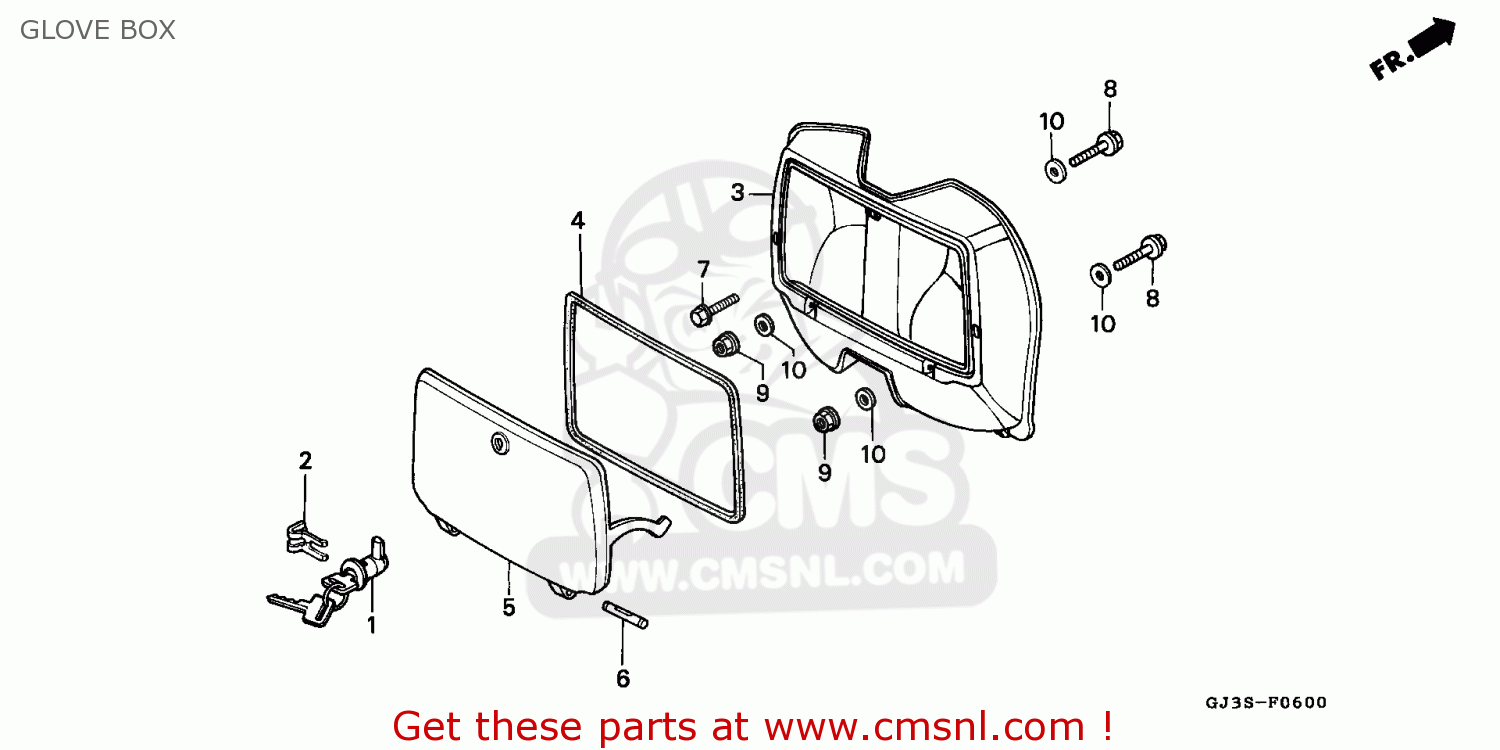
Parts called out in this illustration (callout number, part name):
1	KEY SET,(GLOVE BO
2	SPR DR LOCK KEY
3	GLOVE BOX PB190
4	RUBBER C,SEAL
5	LID,GLOVE*PB190R*
6	PIN,LID INNER BOX
7	BOLT,FLANG,6MM
8	BOLT,CAP,5X16
9	NUT,FLANGE,5MM
10	WASHER,PLAIN,5MM
